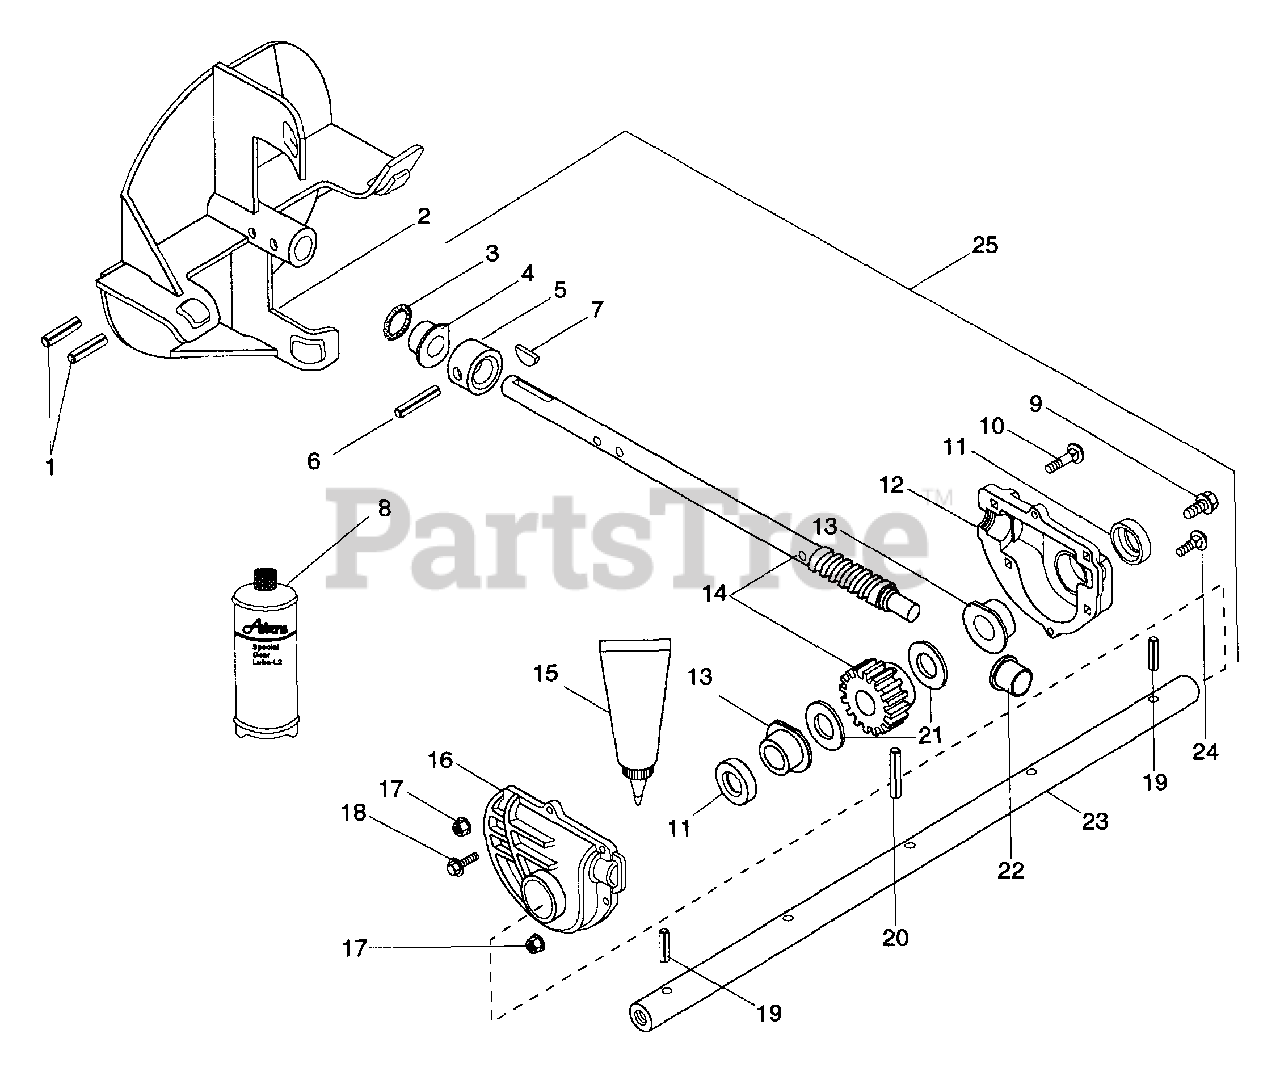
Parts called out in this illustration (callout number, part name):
1	PIN-ROLL .250X1.75
2	FAN - 12"
3	SEAL .750X1.000X.150
4	BSHG-FLG .750X1.000X.750X1.250
5	THRUST COLLAR
6	PIN-GRV .188X1.25 TP A
7	KEY-WDRF .188X.875X.375 SAE11
8	BOTTLE ONLY-S.SCREEN.FOR NO.80
9	SCR-TAP .375-16X .50 HWH PL TR
10	BLT-RDHDSQNK .25-20X1.25 GR5PL
11	SEAL 1.000X1.312X.150
12	GEAR CASE-LH-LARGE BORE
13	BSHG-FLG 1.003X1.5X.625
14	WORM SHAFT & GEAR ASSY
15	LOCTITE 518 GASKET--6ML TUBE
16	GEAR CASE-RH-LARGE BORE
17	NUT-LK-FLG .250-20 PL
18	SCR-TAP 10-24X.75 HWH PL TR
19	PIN-ROLL .188X1.50
20	PIN-GRV .313X1.44 TP C
21	WSHR-HRD-THRS 1.007X1.542X.062
22	BSHG-FLG .502X1X.750
23	SHAFT, RAKE - 24"
24	BLT-RDHDSQNK .25-20X.88 PL
25	GEAR CASE - 24" - ALUMINUM
